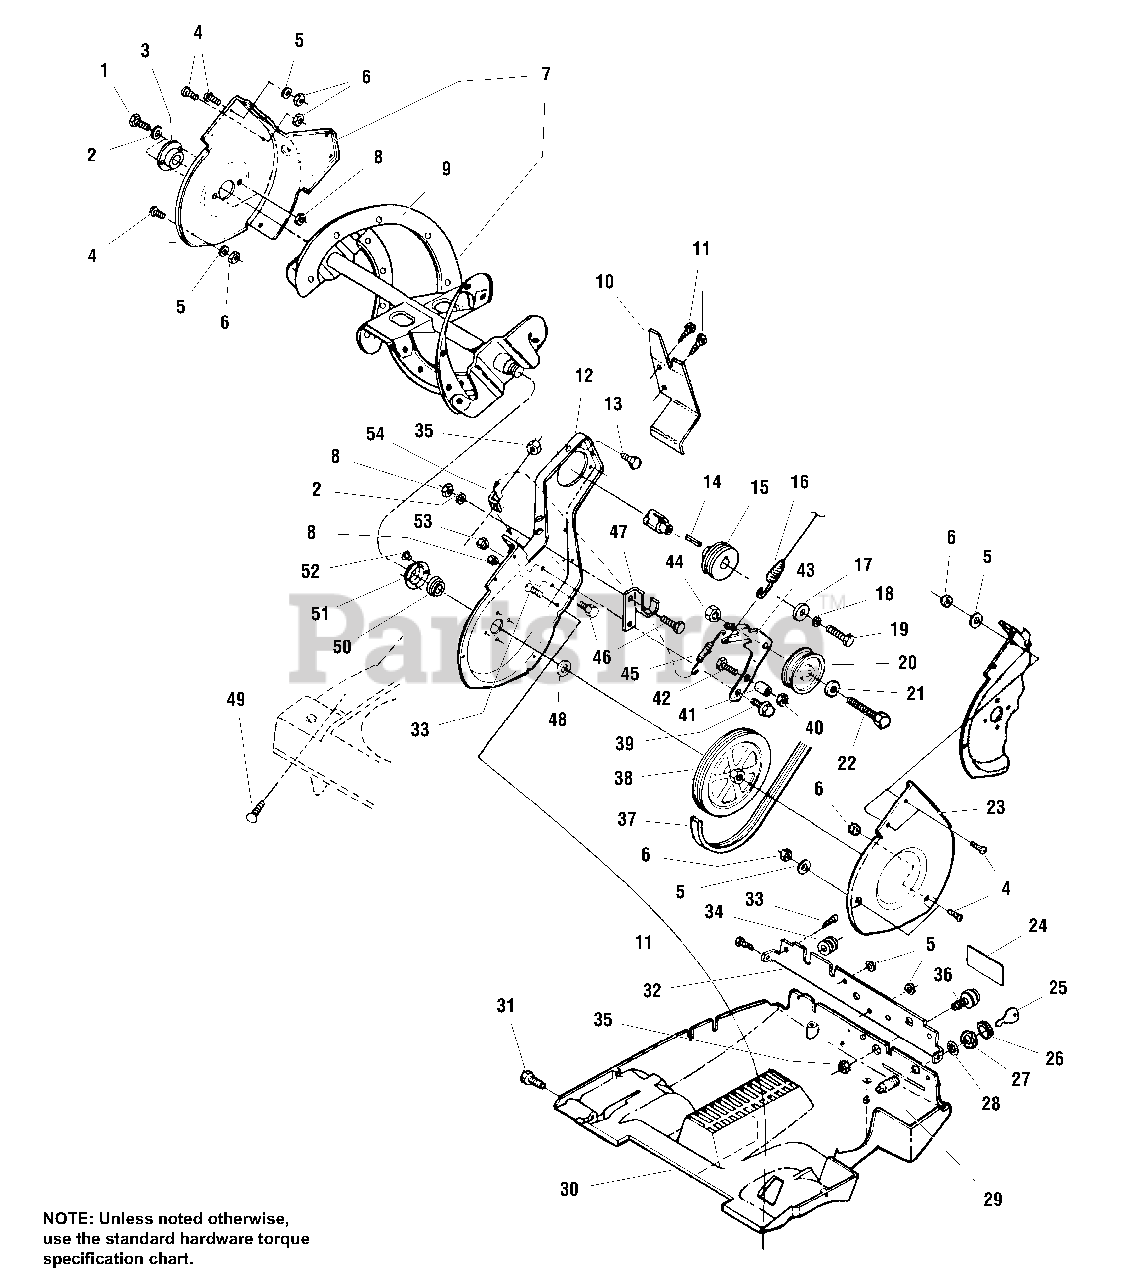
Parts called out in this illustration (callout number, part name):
1	BOLT, Hex, 1/4-20 x 7/8, Gr. 5
2	WASHER, Flat, 1/4
3	BEARING, Plastic
4	SCREW, Phillips, #10-24 x 5/8
5	WASHER, Retaining
6	NUT, #10-24
7	KIT, R.H. Frame & Auger (w/ bearing)
8	NUT, 1/4-20, Nylock
9	KIT, Auger Flighting
10	SHIELD, Belt
11	SCREW, Tap, #10-24 x 1/2
12	FRAME, Left Side
13	BOLT, Hex, 5/16-24 x 5/8
14	KEY, 3/16 Sq. x 1
15	PULLEY, Drive
16	CABLE, Auger Control
17	WASHER, Flat
18	WASHER, Split Lock, 5/16
19	BOLT, Hex, 5/16-24 x 7/8, Gr. 5
20	PULLEY, Idler
21	WASHER, Flat 3/8
22	BOLT, Hex, 3/8-16 x 1-1/2
23	GUARD, Belt
24	DECAL, Choke
25	KEY, Ignition
26	BOOT, Ignition Switch
27	NUT, Hex, Ignition Switch, 5/8-32
28	WASHER, Internal Tooth, 5/8
29	SWITCH, Ignition
30	COWLING, Lower
31	SCREW, Hex, 1/4-20 x 5/8
32	BRACKET, Control Panel
33	SCREW, Tap, #10-24 x 3/4
34	GROMMET, Metal
35	NUT, Keps, 1/4-20
36	PRIMER, Bulb
37	BELT, Drive
38	PULLEY- Drive
39	BOLT, Idler Pivot
40	NUT, Center Lock, 1/4-20
41	ROLLER, Belt Stop
42	BOLT, Hex, 1/4-20 x 1
44	NUT, Serrated, Flange Lock, 3/8
45	SPRING, Extension
46	BOLT, Hex, 1/4-20 x 3/4
47	BRACKET, Belt
49	CARRIAGE BOLT, 1/4-20 x 3/4
51	RETAINER, Bearing
52	RIVET, 1/4
53	NUT, Nylock, 5/16-18
54	CLIP, Spring
